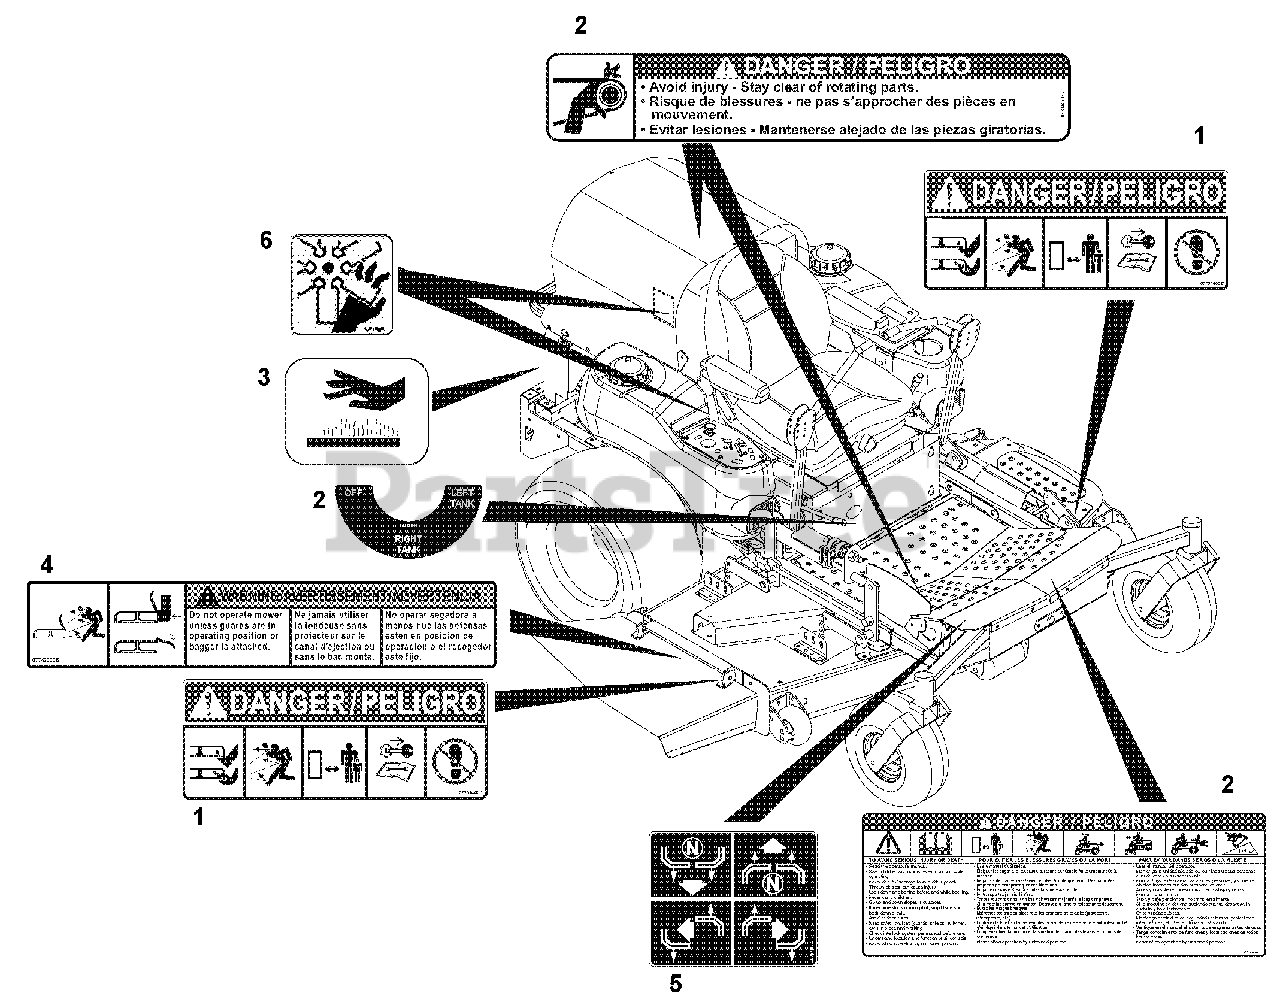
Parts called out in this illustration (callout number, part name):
1	Decal, Mower Pan Head Danger
2	Set, Decal-Common Danger/Fuel
3	Decal-Hot Surface
4	Decal, Warning
5	Decal-Instructional
6	Decal, Danger Fan
